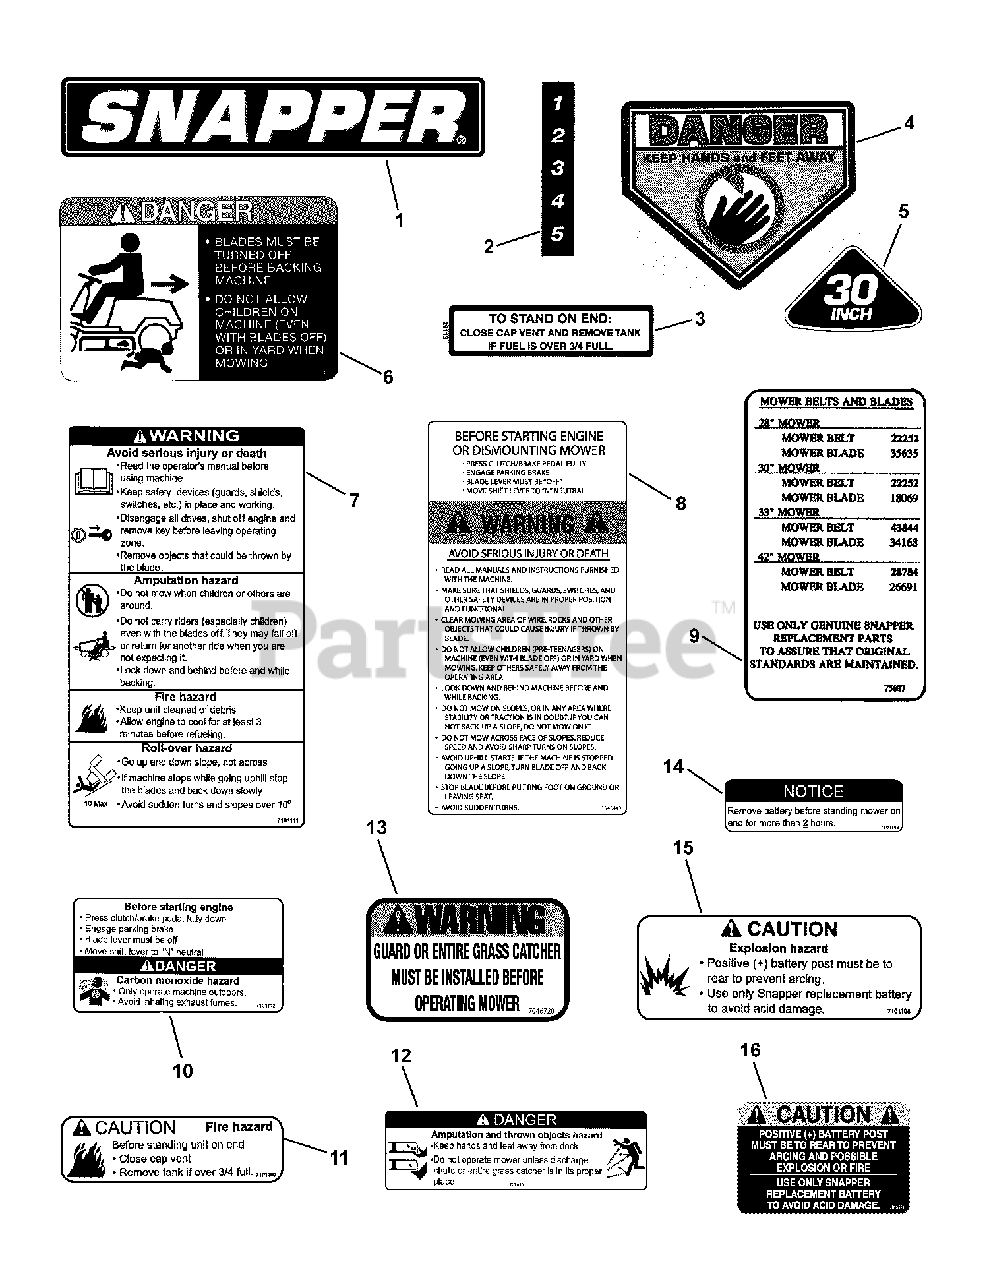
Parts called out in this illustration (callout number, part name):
1	DECAL, SNAPPER
2	DECAL, Height of Cut
3	DECAL, Caution, Fuel Leakage (English)
4	DECAL, Danger, Cut Finger
5	DECAL, 30" Deck
6	DECAL, No Mow in Reverse
7	DECAL, Warning, Safety Panel
8	DECAL, Safety Instructions
9	DECAL, Service Parts, RER Domestic
10	DECAL, Danger, Safety Panel
11	DECAL, Caution, Fuel
12	DECAL, Danger, Deck
13	DECAL, Chute/Deflector
14	DECAL, Battery
15	DECAL, Caution, Battery
16	DECAL, Battery Caution
